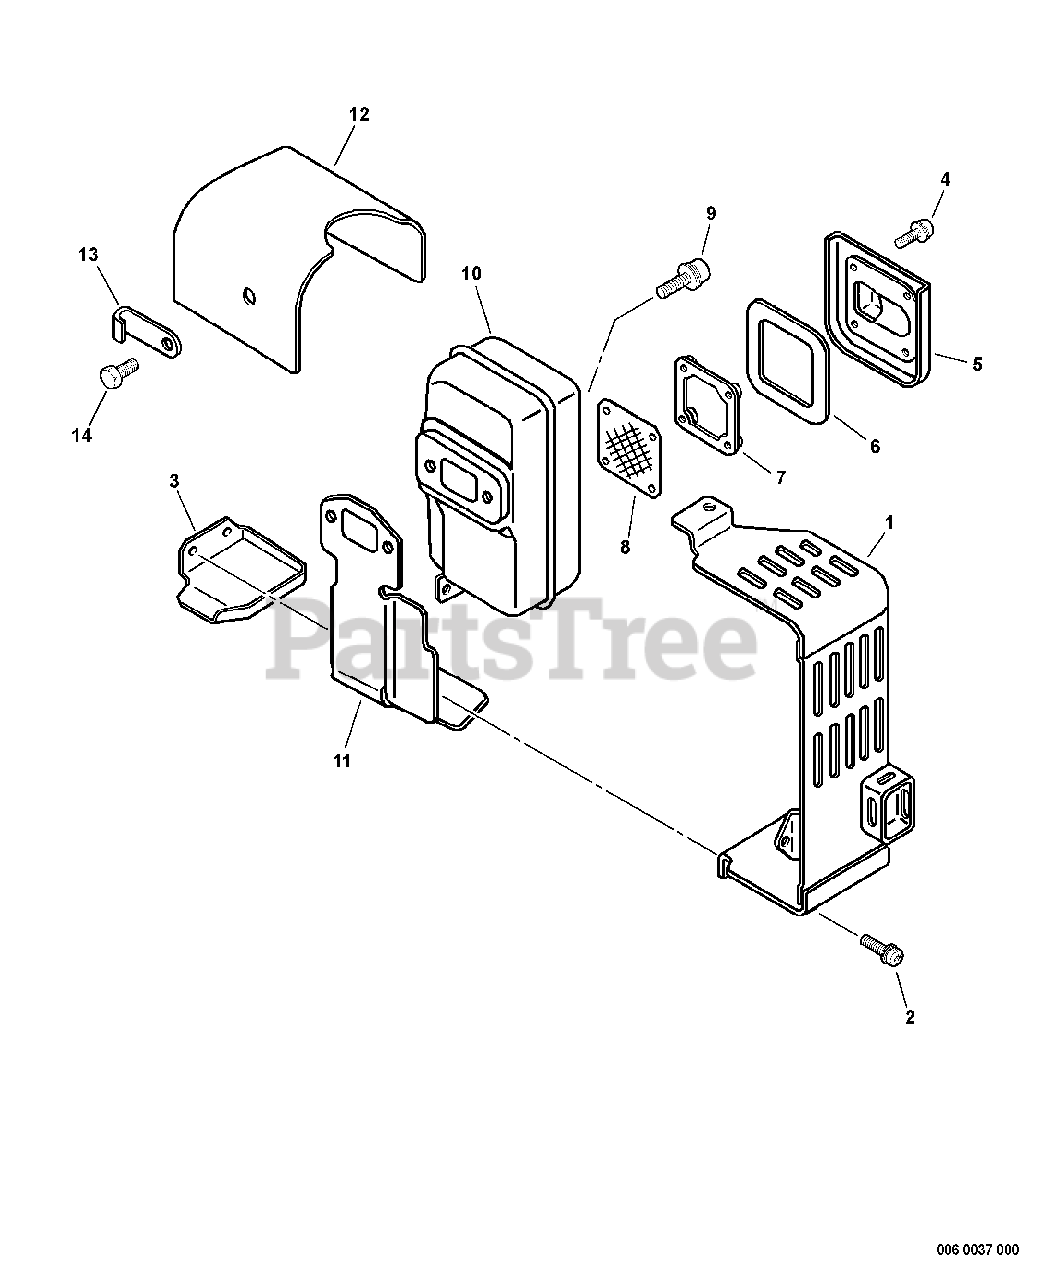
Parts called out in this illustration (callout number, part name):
1	SHIELD, EXHAUST
2	SCREW - 5X14
3	BRACKET, MUFFLER COVER
4	SCREW - 4X16
5	GUIDE, EXHAUST
6	GASKET, EXHAUST
7	RETAINER, SCREEN
8	SCREEN, SPARK ARRESTOR
9	SCREW - 6X20
10	MUFFLER
11	GASKET, EXHAUST
12	SHIELD, CYLINDER
14	BOLT - 6X10
